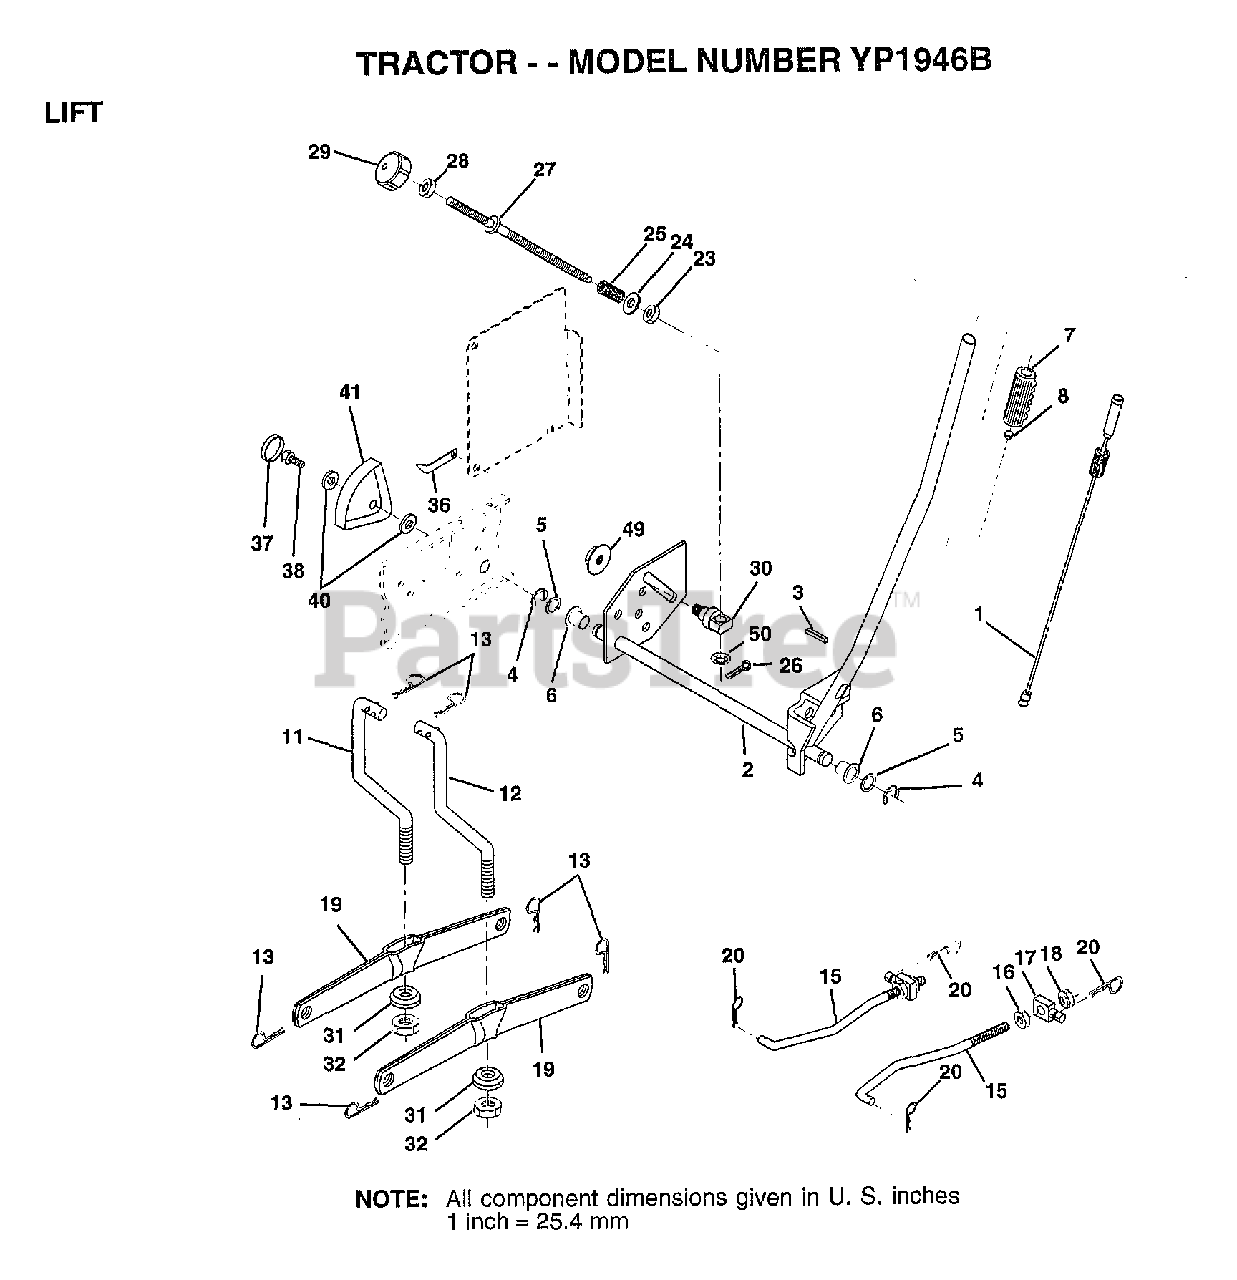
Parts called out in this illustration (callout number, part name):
1	WIRE ASM W.SPRING
2	"SHAFT ASM LIFT,RH"
3	PIN-GROOVE LT
5	WASHER
6	NYLON BEARING
7	GRIP HANDLE
15	LINK.FRONT
16	NUT
17	TRUNION
18	NUT.LK.W/WSH.1/2.
19	ARM SUSP REAR
20	RETAINER.SPRING
23	NUT T
24	WASHER
25	SPRING T
28	NUT
29	KNOB INF 3/8-16
30	TRUNNION
31	BEARING PVT LH
32	NUT.CROWNLOCK.3/8
36	POINTER-INDICAT
37	"PLUG,HOLE"
38	SCREW
40	WASHER
41	HEIGHT INDICATOR
49	NUT.HXFLG.LOCK.
